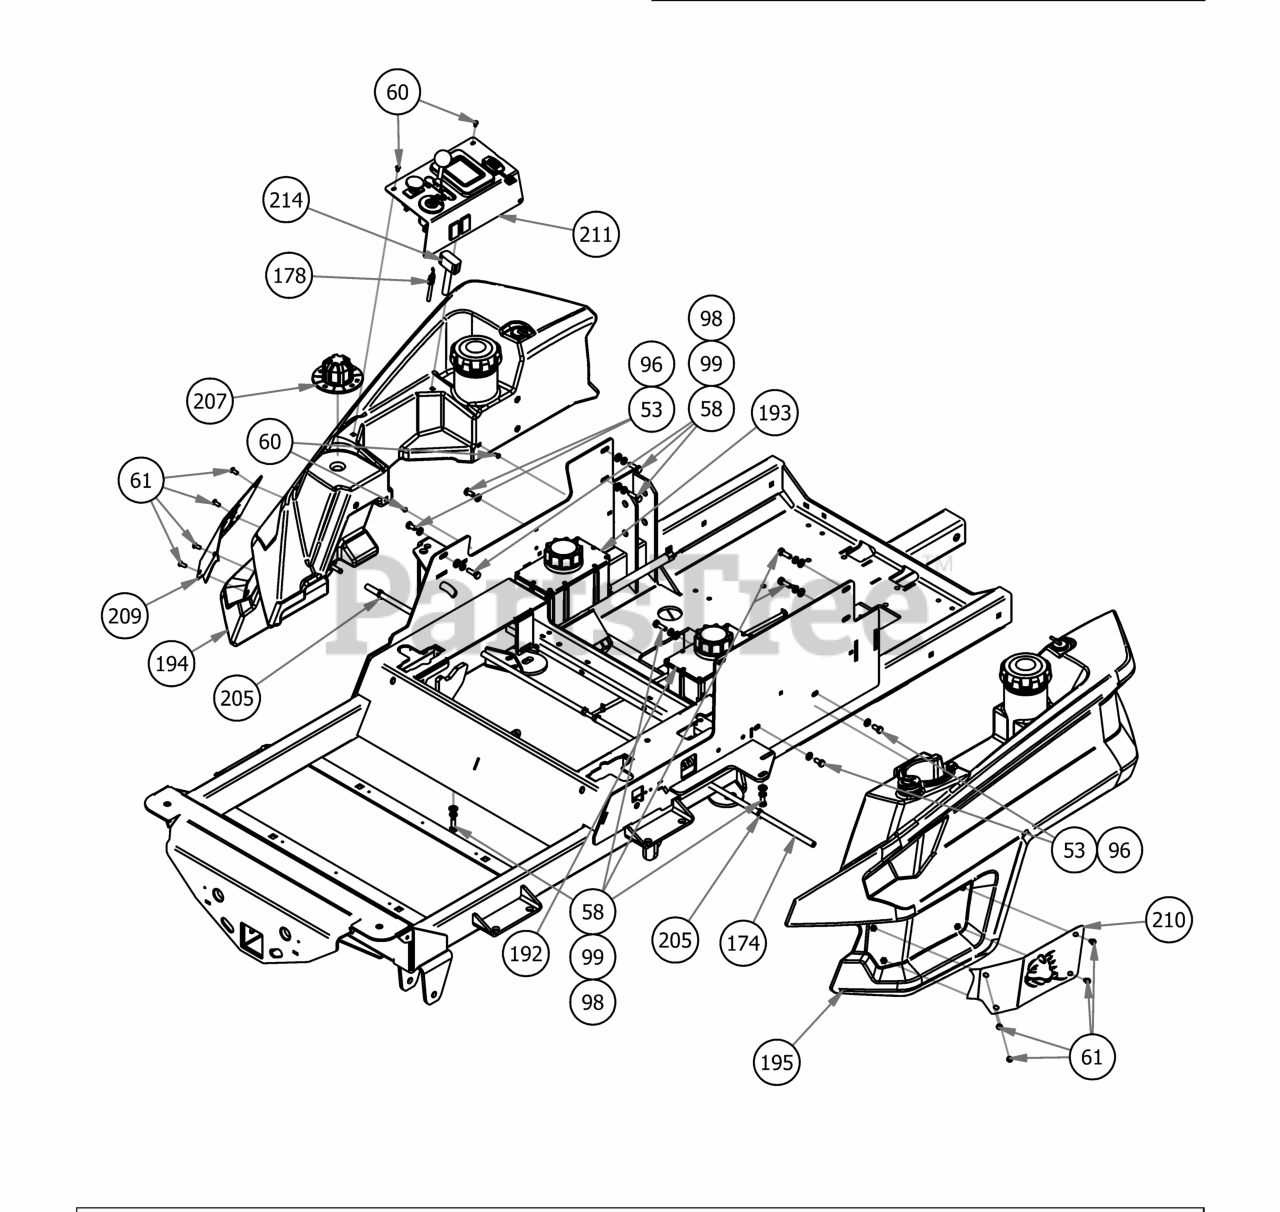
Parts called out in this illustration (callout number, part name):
53	5/16-18 x 5/8 Hex Bolt
58	5/16" x 1" Bolt
60	10-32 x 3/8" Button Socket Head Bolt
61	1/4" x 1/2" BS C/S 18-8 SS
96	1/4" Flat Washer
98	5/16" Flat Washer
99	5/16" Lock Washer
174	2019 Rebel Rogue Renegade Fuel Line for Vanguard & Yamaha
178	Outlaw Throttle Cable
192	LH Rogue Hydro Tank Assy
193	RH Rogue Hydro Tank Assy
194	2019 Right Rebel, Rogue, Renagade Fuel Tank (GAS)
195	2019 Left Rebel, Rogue, Renegade Fuel Tank (GAS)
203	2019 Horizontal Gas Frame
205	2 EAR CLAMP 12.5mm-15mm
207	2019 Deck Height Dial
209	2019 Outlaw Fuel Tank Insert - Right
210	2019 Outlaw Fuel Tank Insert - Left
211	Renegade Control Panel Assembly
214	2019 LCD Panel Harness-Renegade
